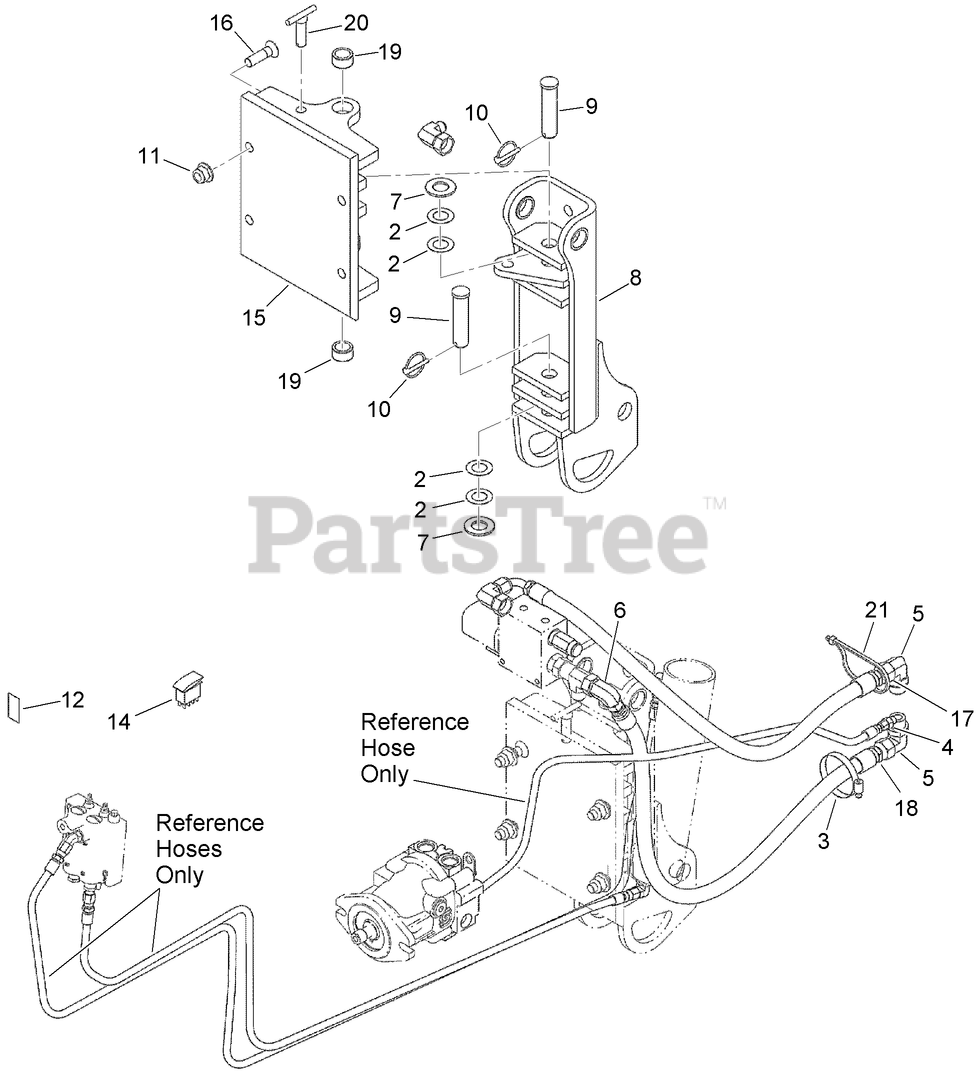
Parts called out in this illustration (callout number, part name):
2	WASHER-FLAT
3	CLAMP-Hose #56
4	CONNECTOR-Str Thd 3/8, 37FL-ORB 3/8
5	ELBOW-90 Adj 37FL 3/4 Tube
6	FITTING-ELBOW, 90
7	WASHER-FLAT
8	PIVOT - Plow
9	PIN-PIVOT
10	PIN-KLIK
11	NUT-HHF
12	DECAL - Plow Switch
14	SWITCH - SPST
15	SLIDE-QUICK ATTACH
16	SCREW-HSFH
17	HOSE ASSEMBLY - Hydraulic
18	HOSE ASSEMBLY - Hydraulic
19	BUSHING-UPPER
20	PIN - Pivot Lock
21	STRAP-TIE
